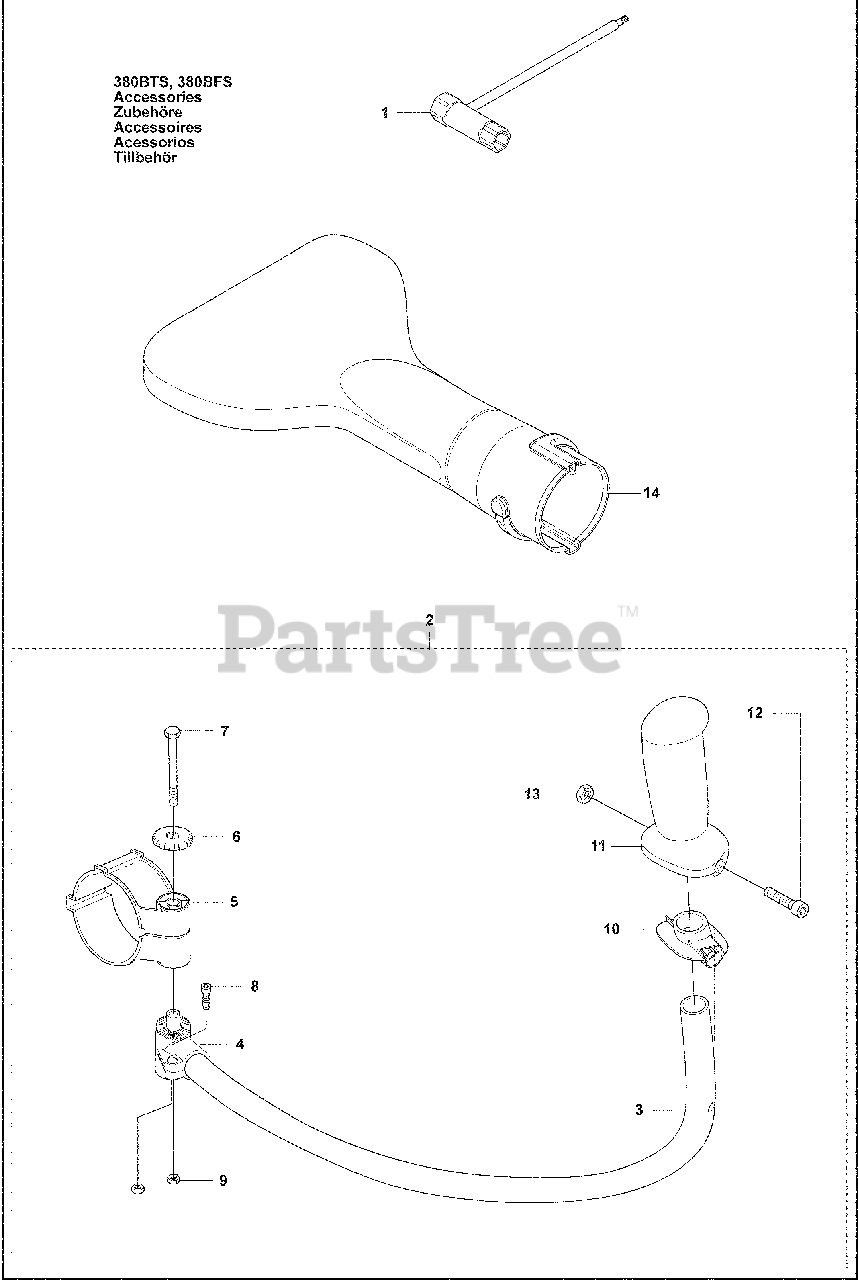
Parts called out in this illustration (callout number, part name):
1	SOCKET
2	Handle, 170 BT
5	HOLDER TH
6	Air Filter Cover Knob
8	Screw, MC6S 5 X 10
9	Hex Nut, M5 X .80 DIN
13	Hex Nut, M5 X .80 DIN
14	Flat Nozzle
